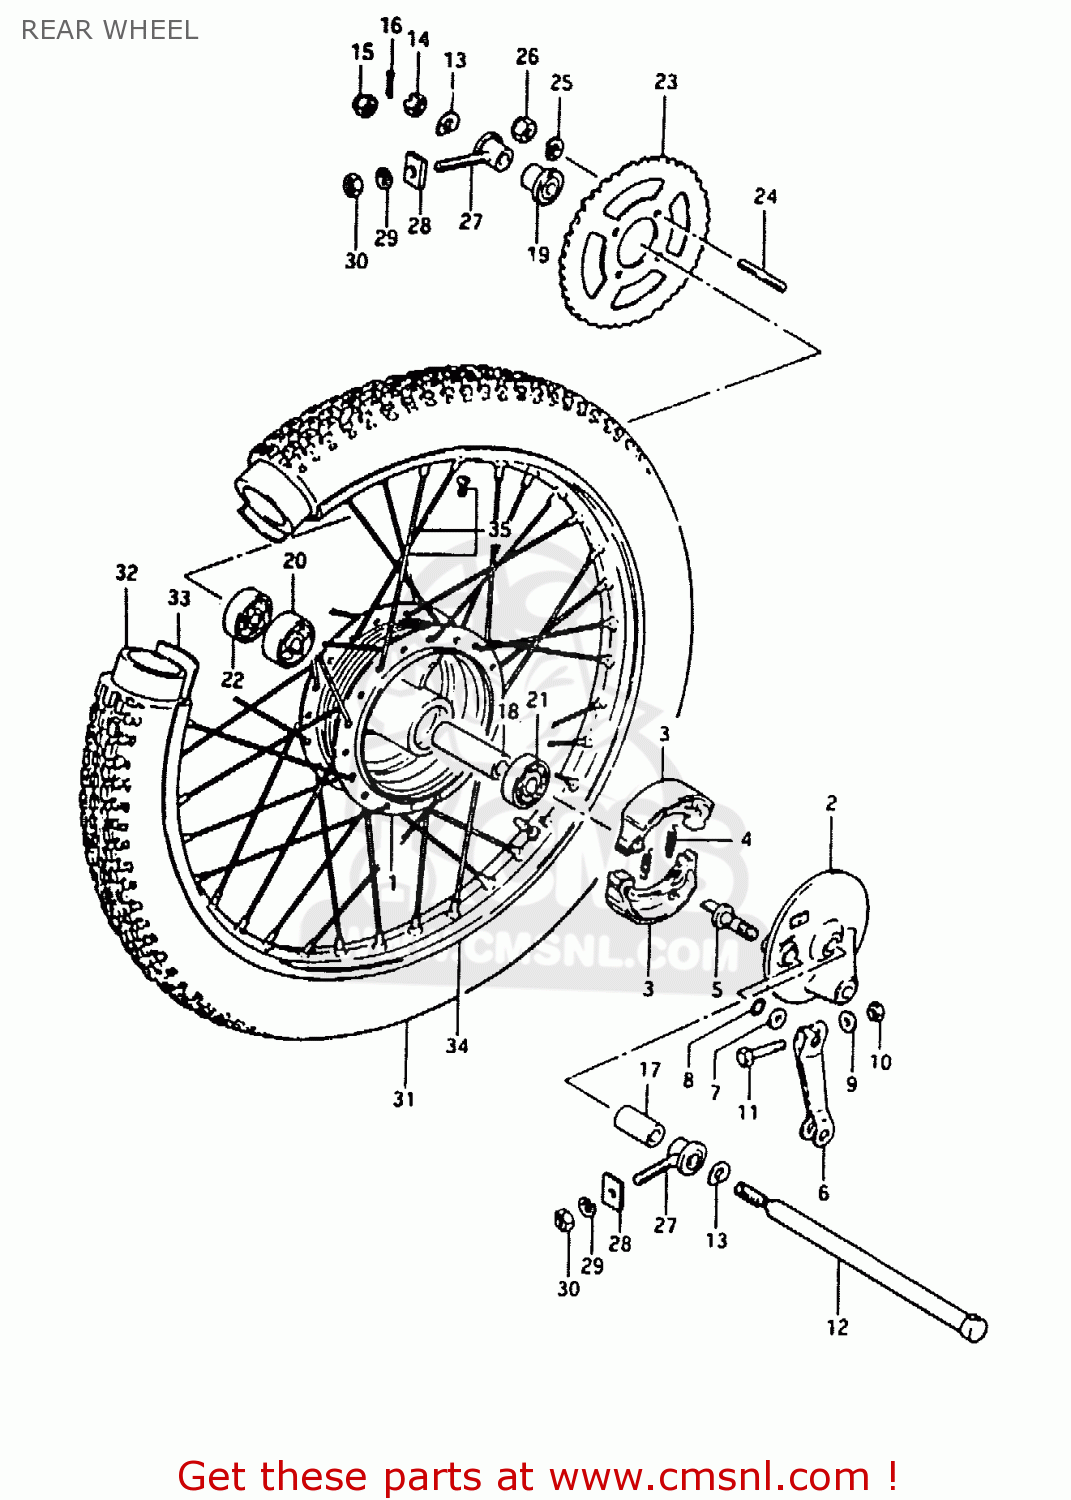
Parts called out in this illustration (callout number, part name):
1	DRUM SET,REAR HUB
2	PANEL,REAR BRAKE ANCHOR
3	SHOE,BRAKE (MCA)
4	SPRING(L:34)
5	CAM,FRONT BRAKE
6	LEVER,RR BRAKE CAM
7	WASHER (14.5X22X1.6)
8	O-RING (D:2.4 ID:13.8)
9	WASHER
10	NUT
11	BOLT(6X33)
12	AXLE,RR
13	WASHER,RR AXLE
14	NUT 12MM
16	COTTER PIN
17	SPACER, AXLE RH
18	SPACER (12.6X19X79)
19	SPACER, REAR AXLE LH
20	BEARING
21	BEARING
22	BEARING
23	SPROCKET, REAR (NT:49)
24	BOLT
25	LOCK WASHER
26	NUT
27	ADJUSTER, CHAIN
28	ADJUSTER,CHAIN
29	LOCK WASHER
30	NUT
31	TIRE
32	TUBE,INNER
33	PROTECTOR,INNER TUBE
34	RIM, WHEEL
35	SPOKE SET,REAR WHEEL
